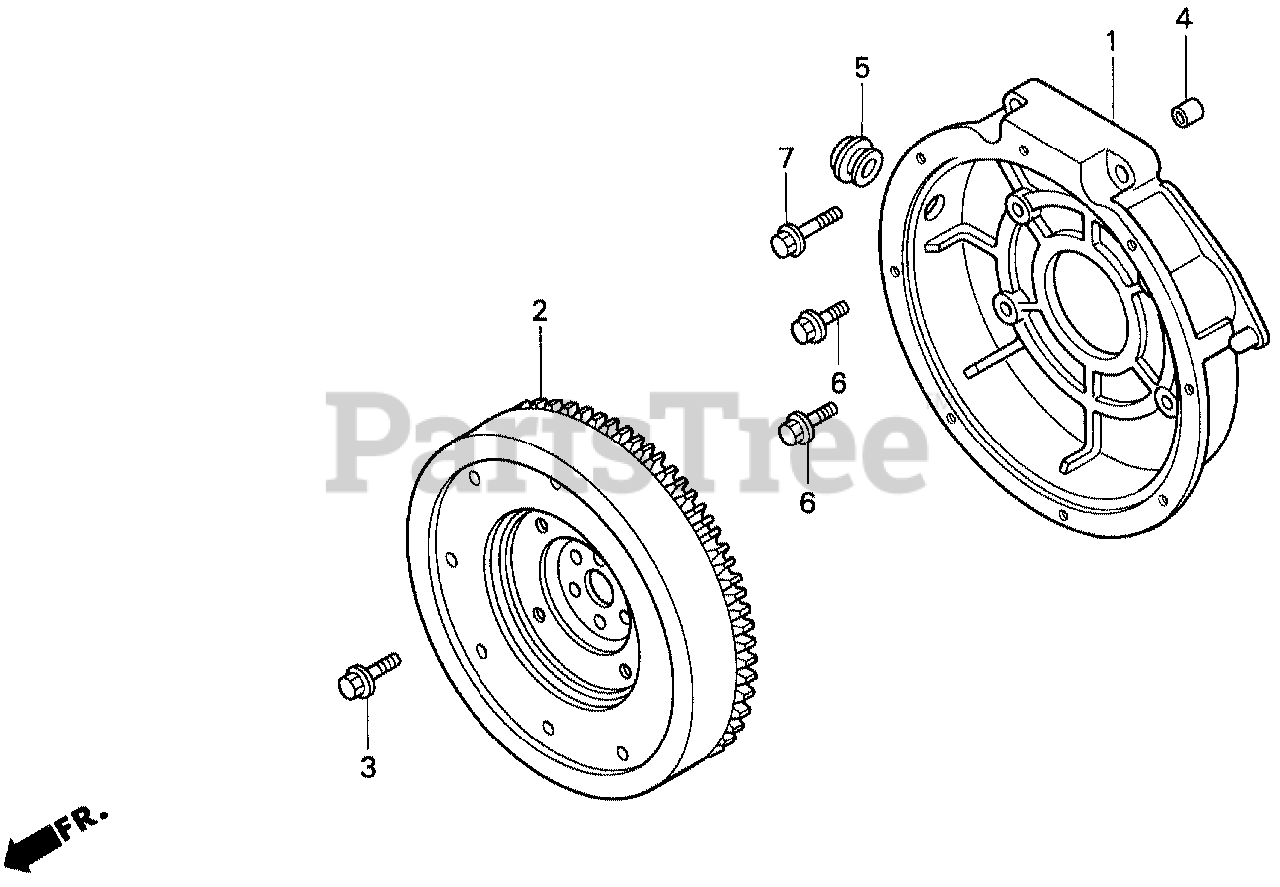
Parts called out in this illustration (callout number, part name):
1	HOUSING, FLYWHEEL
3	BOLT (12MM)
4	PIN, DOWEL (14X10)
6	BOLT, FLANGE (12X32)
7	BOLT, FLANGE (12X50)
